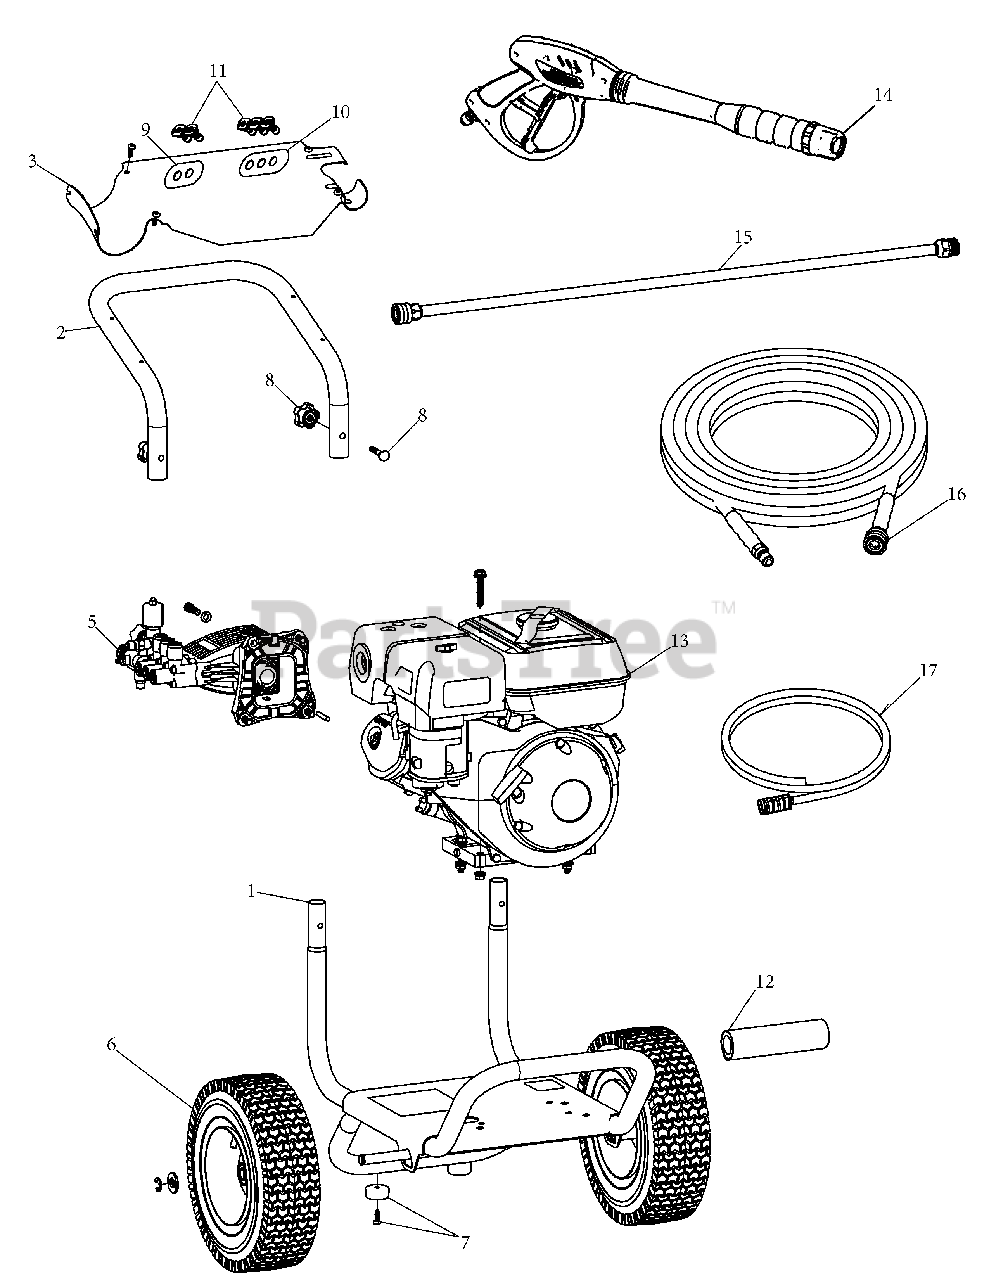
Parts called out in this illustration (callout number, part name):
1	Base Assembly, Frame
2	Handle, Upper
3	Panel, Dashboard w/Label
5	Pump Assembly
6	Wheel Assembly
8	Knob, Handle Mounting
9	Nozzle Holder, 2pc
10	Nozzle Holder, 3pc
11	Nozzle Set 5pc
12	Grip, Handle
13	Engine Assembly, Honda
14	Gun, Spray Dial N Wash
15	Wand, Spray Gun 31"
16	Hose, Spray 50'
17	Hose, Soap w/Filter
